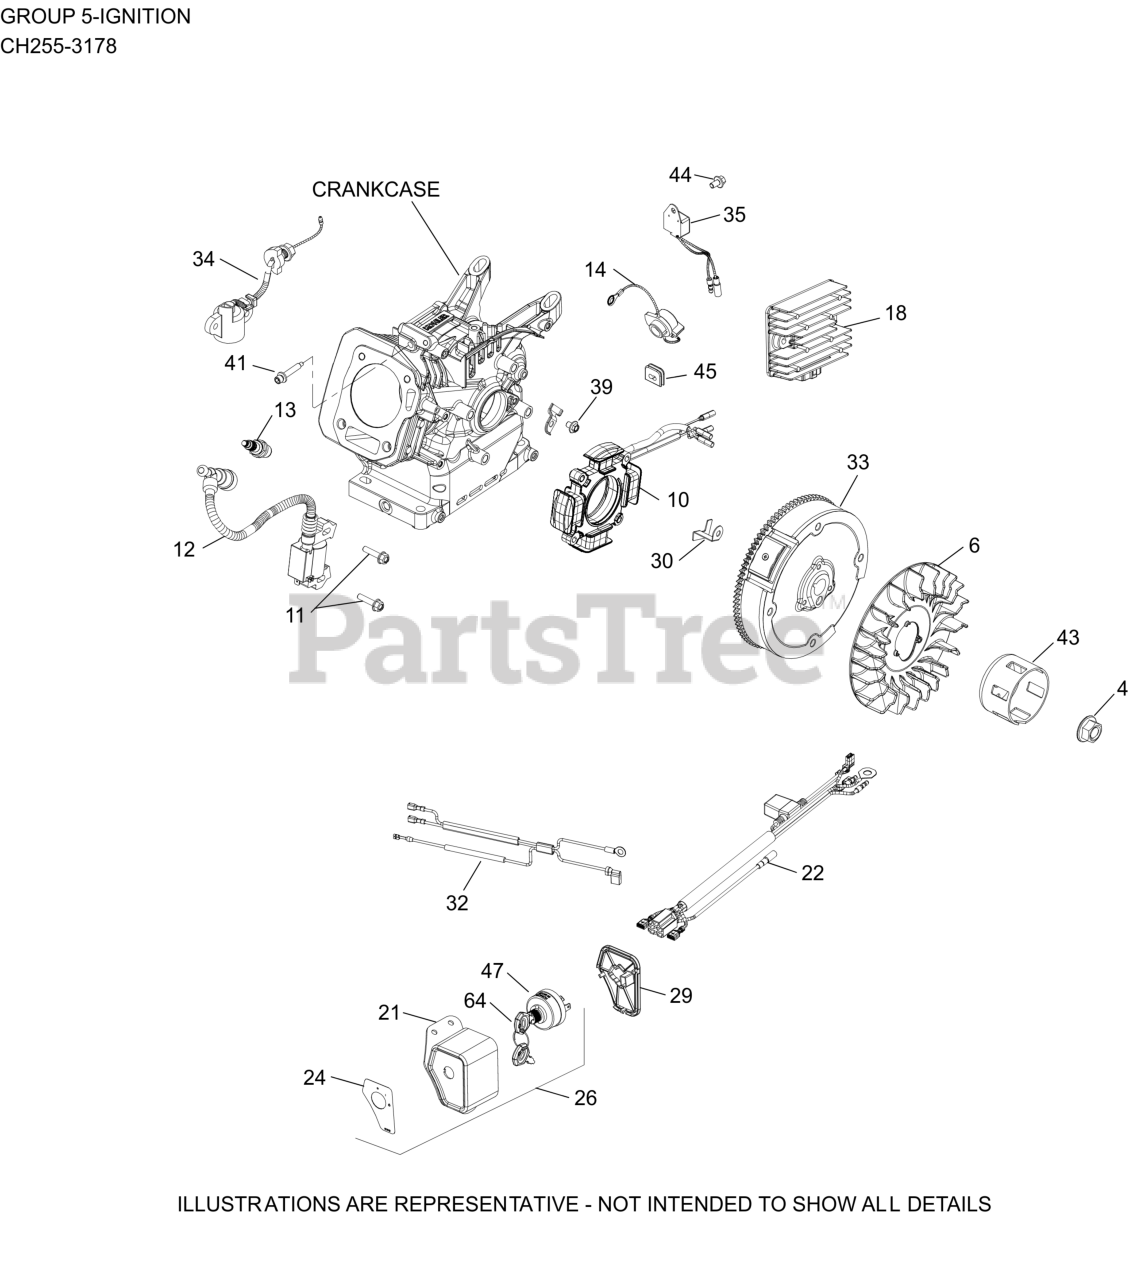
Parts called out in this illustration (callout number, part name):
4	NUT, FLYWHEEL (W/SERRATIONS)
6	FAN, FLYWHEEL
10	STATOR ASSEMBLY, 3 POLE
11	SCREW, M6 X 25-(#25086436S)
12	MODULE, IGNITION
13	PLUG SPARK 12MM RFI
18	REGULATOR, 10 AMP
21	KIT, KEYBOX HOUSING ASSEMBLY
22	HARNESS, WIRING ASSEMBLY (10 AMP)
24	LABEL, KEY BOX
26	KIT, KEY BOX ASSEMBLY
29	COVER, KEY BOX
30	BRACKET, FIXED STATOR WIRE
32	HARNESS, REGULATOR WIRING ASSY
33	FLYWHEEL ASSEMBLY - 10 AMP
34	SWITCH, OIL SENSOR ASSEMBLY
35	CONTROL, OIL ALERT UNIT
39	SCREW, M6 X 8
41	SCREW, HEX SOCKET HEAD CAP
43	CUP, STARTER
44	SCREW, FLG M6X1.0X10
45	GROMMET, STATOR WIRE
47	SWITCH, KEY ASSEMBLY
64	KIT, KEY PLASTIC HANDLE (2 PC)
